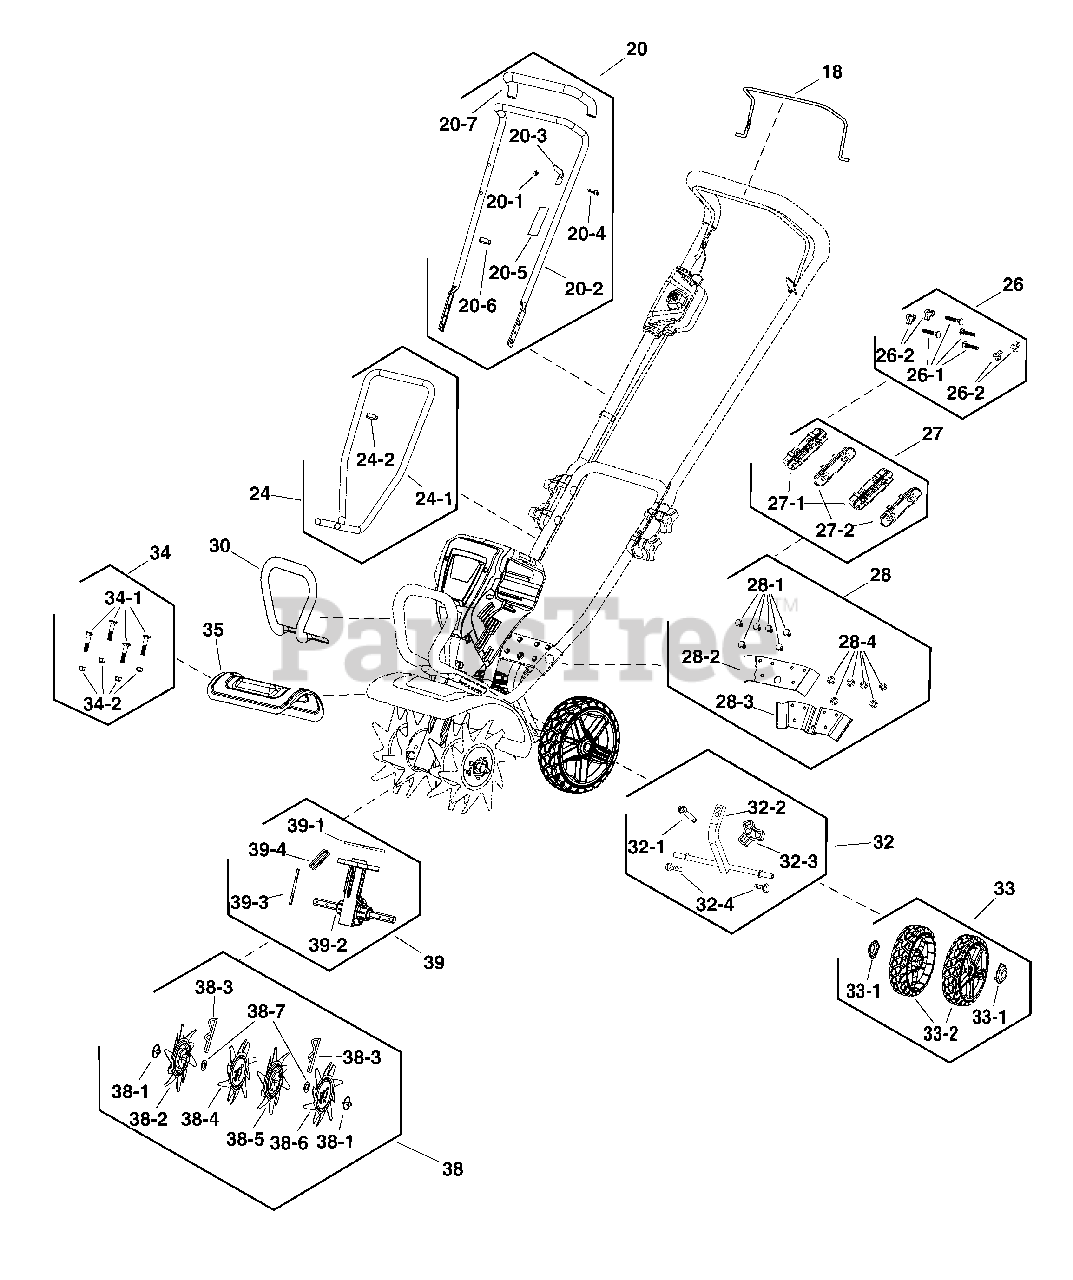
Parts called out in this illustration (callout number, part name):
18	RELEASE LEVER
20	KIT, UPPER HANDLE
20-1	NUT
20-2	HANDLE, Upper
20-3	BRACKET
20-4	SCREW
20-5	WARNING LABEL
20-6	BRACKET
20-7	GRIP, Foam
24	KIT, LOWER HANDLE
24-1	HANDLE, Lower
24-2	BRACKET
26	KIT, HANDLE HARDWARE
26-1	BOLT
26-2	KNOB
27	KIT, HANDLE BRACKETS
27-1	HANDLE BRACKET INSIDE
27-2	HANDLE BRACKET OUTSIDE
28	KIT, HANDLE SUPPORT
28-1	BOLT
28-2	PLATE
28-3	PLATE
28-4	NUT
32	KIT, WHEEL AXLE
32-1	BOLT
32-2	PIN
32-3	KNOB
32-4	BOLT
33	KIT, WHEELS
33-1	WHEEL
33-2	COVER, Wheel
34	KIT, GUARD HARDWARE
34-1	BOLT
34-2	NUT
35	TINE GUARD
38	KIT, TINES
38-1	KLIK PIN
38-2	TINE
38-3	PIN, Cotter
38-4	TINE
38-5	TINE
38-6	TINE
38-7	PAD
39	KIT, GEARBOX
39-1	GASKET
39-2	GEARBOX
39-3	PIN
39-4	GEAR, Drive
